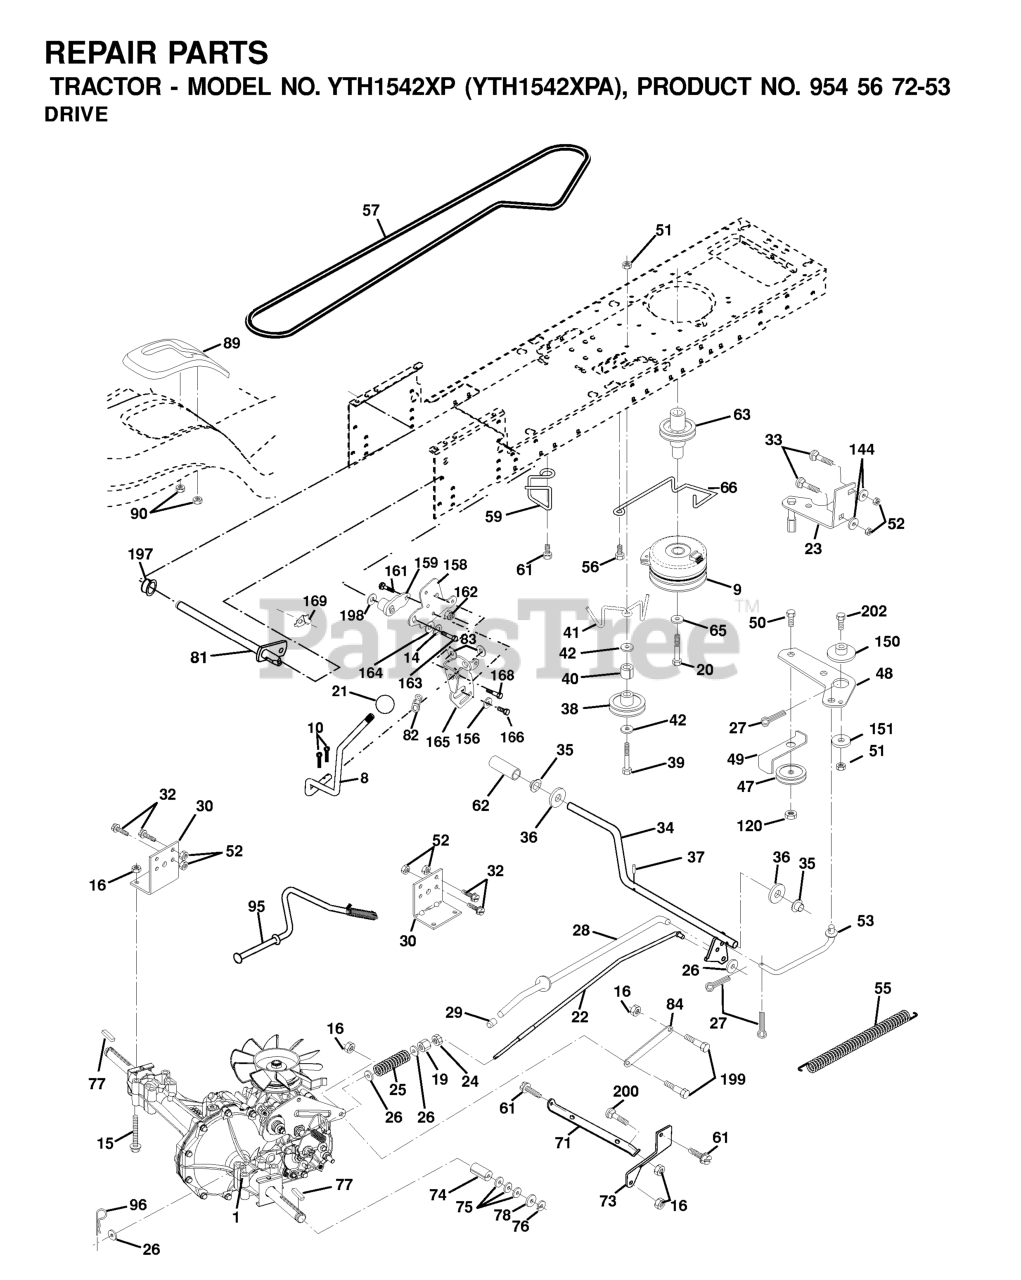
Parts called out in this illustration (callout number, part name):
8	ROD SHIFT FENDER ADJUST STLT
9	ELECTRIC CLUTCH
10	PIN COTTER
14	LOCKWASHER
15	BOLT HEX 5/16-18 GR 5
16	NUT.71038.31-18.HEX.NYLOCK
19	NUT
21	KNOB.DELUXE.(PISTOL.GRIP).BLAC
22	ROD BRAKE HYDRO
24	NUT
25	SPRING ROD LT
26	WASHER
27	COTTER PIN
28	ROD, PARKING BRAKE
29	PLUNGER CAP
30	BRKT, TRNSXLE MNT 20"
32	BOLT
33	RP BOLT 5/16-18 X3/4 ZN/YEL GR
34	SHAFT, FOOT PEDAL
35	BEARING.NYLON
37	DRIVE PIN
38	PULLEY.FLAT
39	BOLT
40	SPACER, SPLIT
41	KEEPER, BELT IDLER
42	WASHER
47	IDLER PULLEY
48	BELLCRANK, CLUTCH
49	RETAIN BELT
50	BOLT
52	LOCKNUT
53	LINK, CLUTCH LT
55	SPRING, RETURN LT
56	SCREW THDROL 3/8-16 X 1-1/2
57	DRIVE BELT, LTH & YTH TRACTORS
59	KEEPER, BELT CENTER
61	SCREW 3/8-16X3/4
62	PEDAL COVER T
63	PULLEY, ENGINE
65	LOCKWASHER
66	KEEPER BELT ENGINE
71	STRAP TORQUE LH HYDRO
73	STRAP TORQUE RH HYDRO
74	SPACER AXLE
77	SQUARE KEY
81	SHAFT ASM CROSS TAPERED
82	SHIFT SPRING
83	WASHER
84	LINK TRANSAXLE
89	SHIFT CONSOLE
90	NUT.PUSH.3/16
95	CONTROL ASM. BYPASS HYDRO
96	RETAINER M
120	NUT LOCK FLG 3/8-16 UNC
144	Washer 11/32 x 5/8 x 16 Ga SD
150	SPACER, RETAINER
151	WASHER 12/32X2X10GA
156	WASHER.SRRTD.5/16
158	BRACKET
159	HUB
161	BOLT
162	NUT.CROWNLOCK.1/4
164	Washer 5/8 x .281 x 10 Ga.
165	RP BRACKET
168	BOLT.SHOULDER.5/16-18X
169	PLATE.FASTENING.CROSS.SHAFT
197	NYLINER SNAP 5/8" ID
198	WASHER.NYL.7/8IDX.105"HYD CR
199	BOLT SHOULDER 5/16-18 UNC
202	BOLT.3/8-16X1.50
